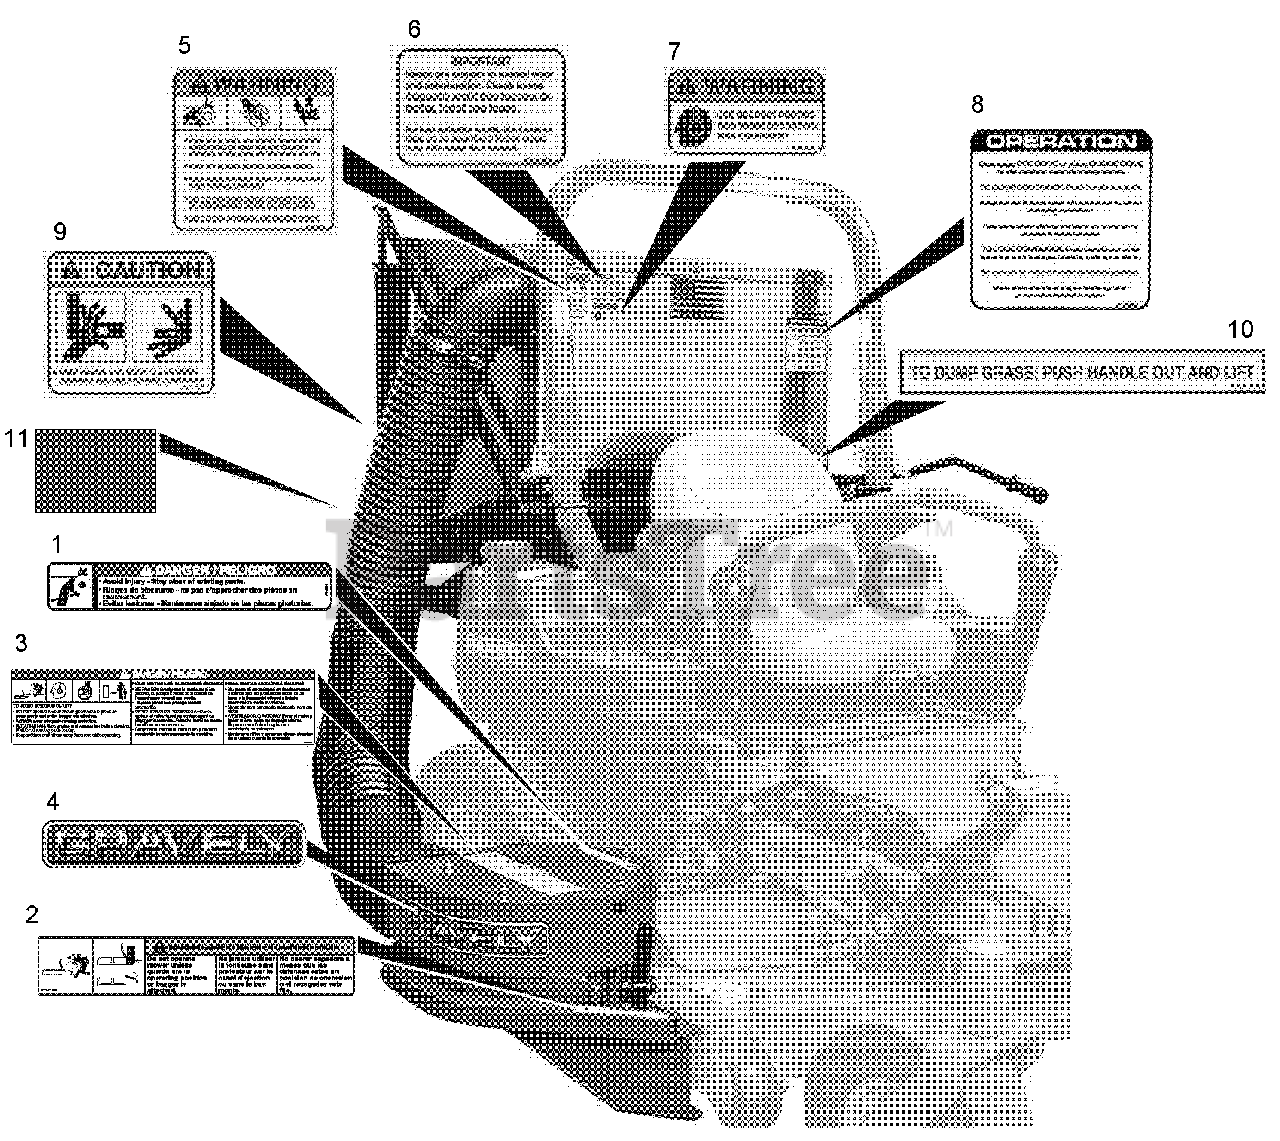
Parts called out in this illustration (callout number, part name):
1	Decal, Danger
2	Decal, Warning
3	Decal, Caution, Grass Pump
4	Decal, Gravely
5	Decal, Warning
6	Decal, Important
7	Decal, Hearing Warning
8	Decal, Operation
9	Decal, Pinch Point Caution
10	Decal, Lift Handle Instruction
11	Decal, Reflective
